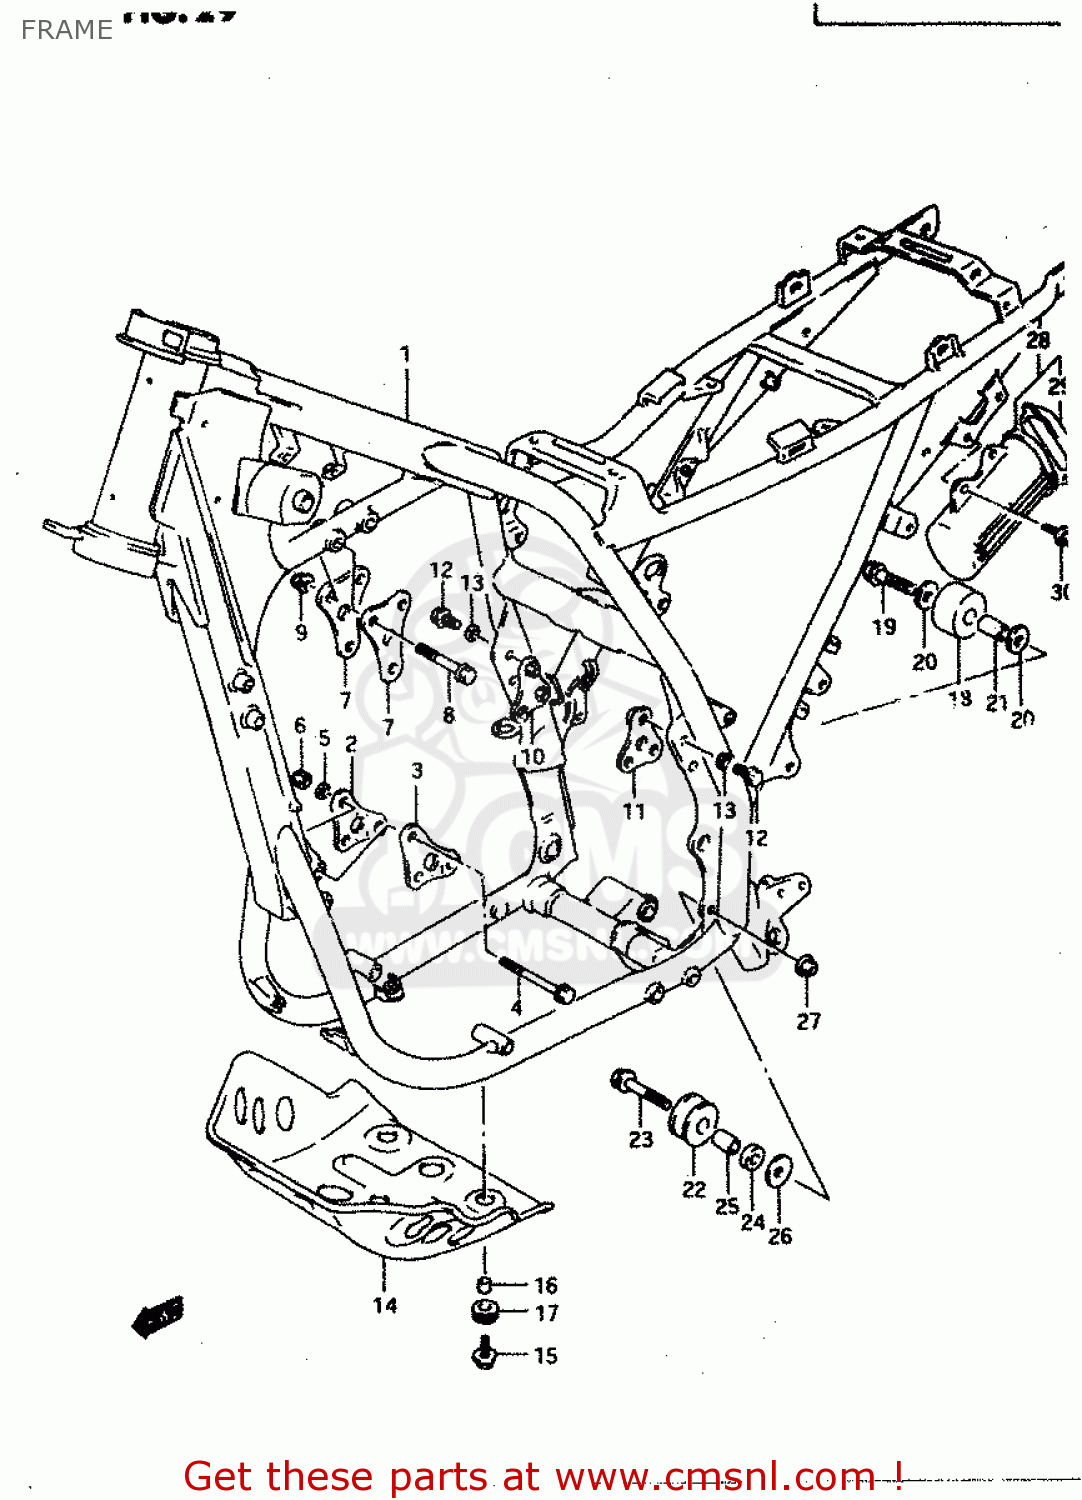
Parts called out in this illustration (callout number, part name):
1	FRAME COMP
2	PLATE,ENG MTG FR,R
3	PLATE,ENG MTG FR,L
4	BOLT(8X72)
5	LOCK WASHER
6	NUT
7	PLATE,ENGINE MOUNTING,UPPER
8	BOLT(8X50)
9	NUT
10	PLATE,ENG MTG RR,R
11	PLATE,ENG MTG RR,L
12	BOLT(8X20)
13	LOCK WASHER
14	PROTECTOR,ENGINE
15	BOLT 6X20
16	SPACER (7X9X7)
17	CUSHION
18	ROLLER,CHAIN CONTROL
19	BOLT(8X41)
20	WASHER (8.2X24X1.6)
21	SPACER (8.6X13.8X28)
22	ROLLER,CHAIN CONTROL
23	BOLT 8X50
24	SPACER(8.5X15X8.5)
25	SPACER(8.6X12X25.5)
26	WASHER
27	NUT
28	HOLDER,TOOL
29	CAP,HOLDER
30	BOLT(6X16)
